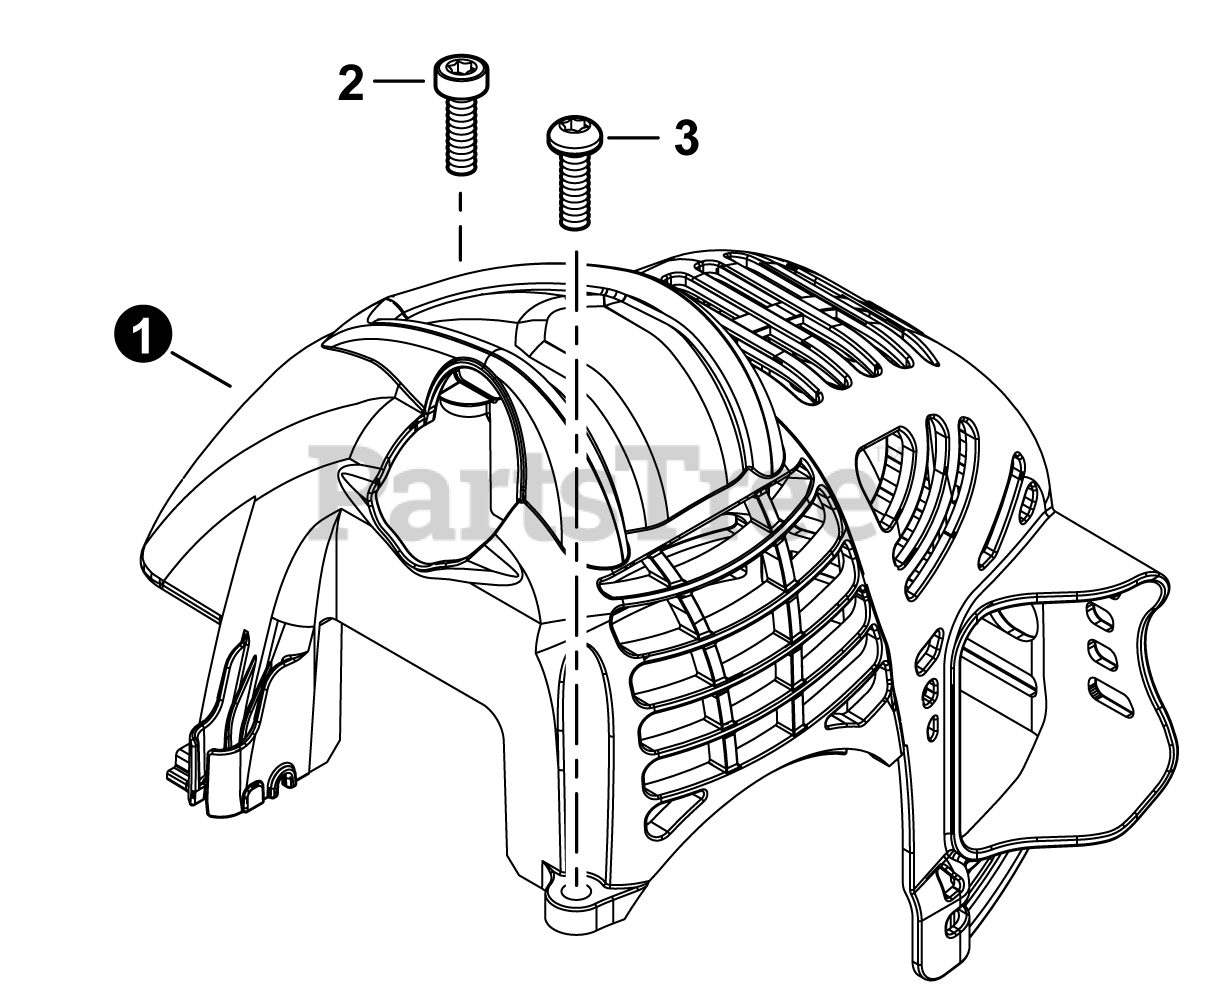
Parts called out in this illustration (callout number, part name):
1	COVER, ENGINE
2	BOLT, TORX 5x16
3	BOLT, TORX 5x16
